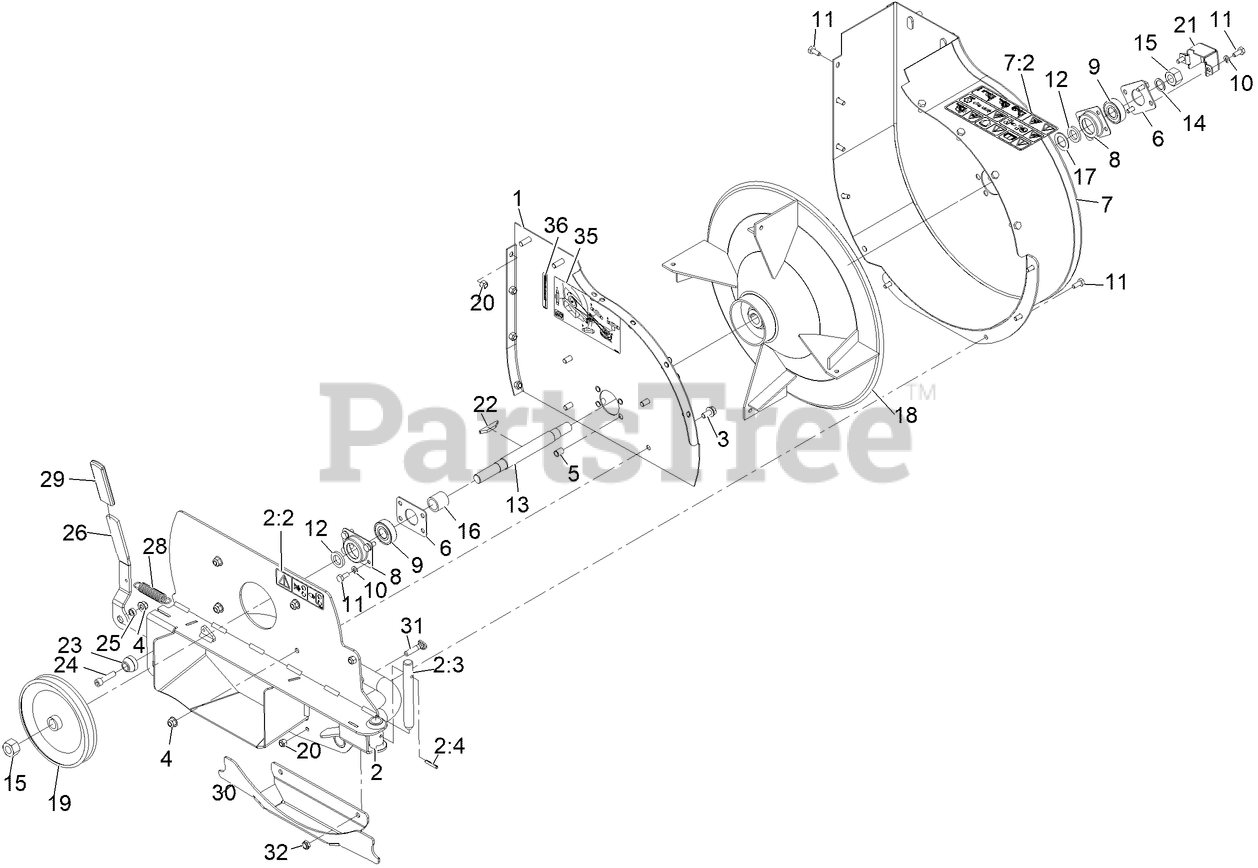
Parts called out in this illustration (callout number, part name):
1	MOUNTING PLATE ASM
2	BLOWER PIVOT ASM
2:2	DECAL-COVER, MISSING
2:3	PIN-BLOWER PIVOT
2:4	PIN-SPRING
3	SCREW-HHF
4	NUT-HF, NI
5	NUT-CLINCH
6	PLATE-COVER
7	BLOWER HOUSING OUTER ASM
7:2	DECAL-WARNING, BLOWER
8	CUP-BEARING
9	BEARING-BALL
10	WASHER-LOCK
11	SCREW-HH
12	SPACER-BEARING
13	SHAFT-BLOWER
14	WASHER-FLAT
15	NUT-HEX
17	WASHER-THRUST
18	IMPELLER ASM
19	PULLEY-TRANSAXLE
20	NUT-LOCK, NI
21	COVER-SHAFT
23	PIN-GUIDE
24	SCREW-HSH
25	SPACER-ARM, IDLER
26	HANDLE
28	SPRING-RETURN, PEDAL
30	PLATE-SKID
31	SCREW-HANDLE
32	NUT-LOCK, NI
35	DECAL-BLOWER BELT ROUTING
36	DECAL-WARNING
